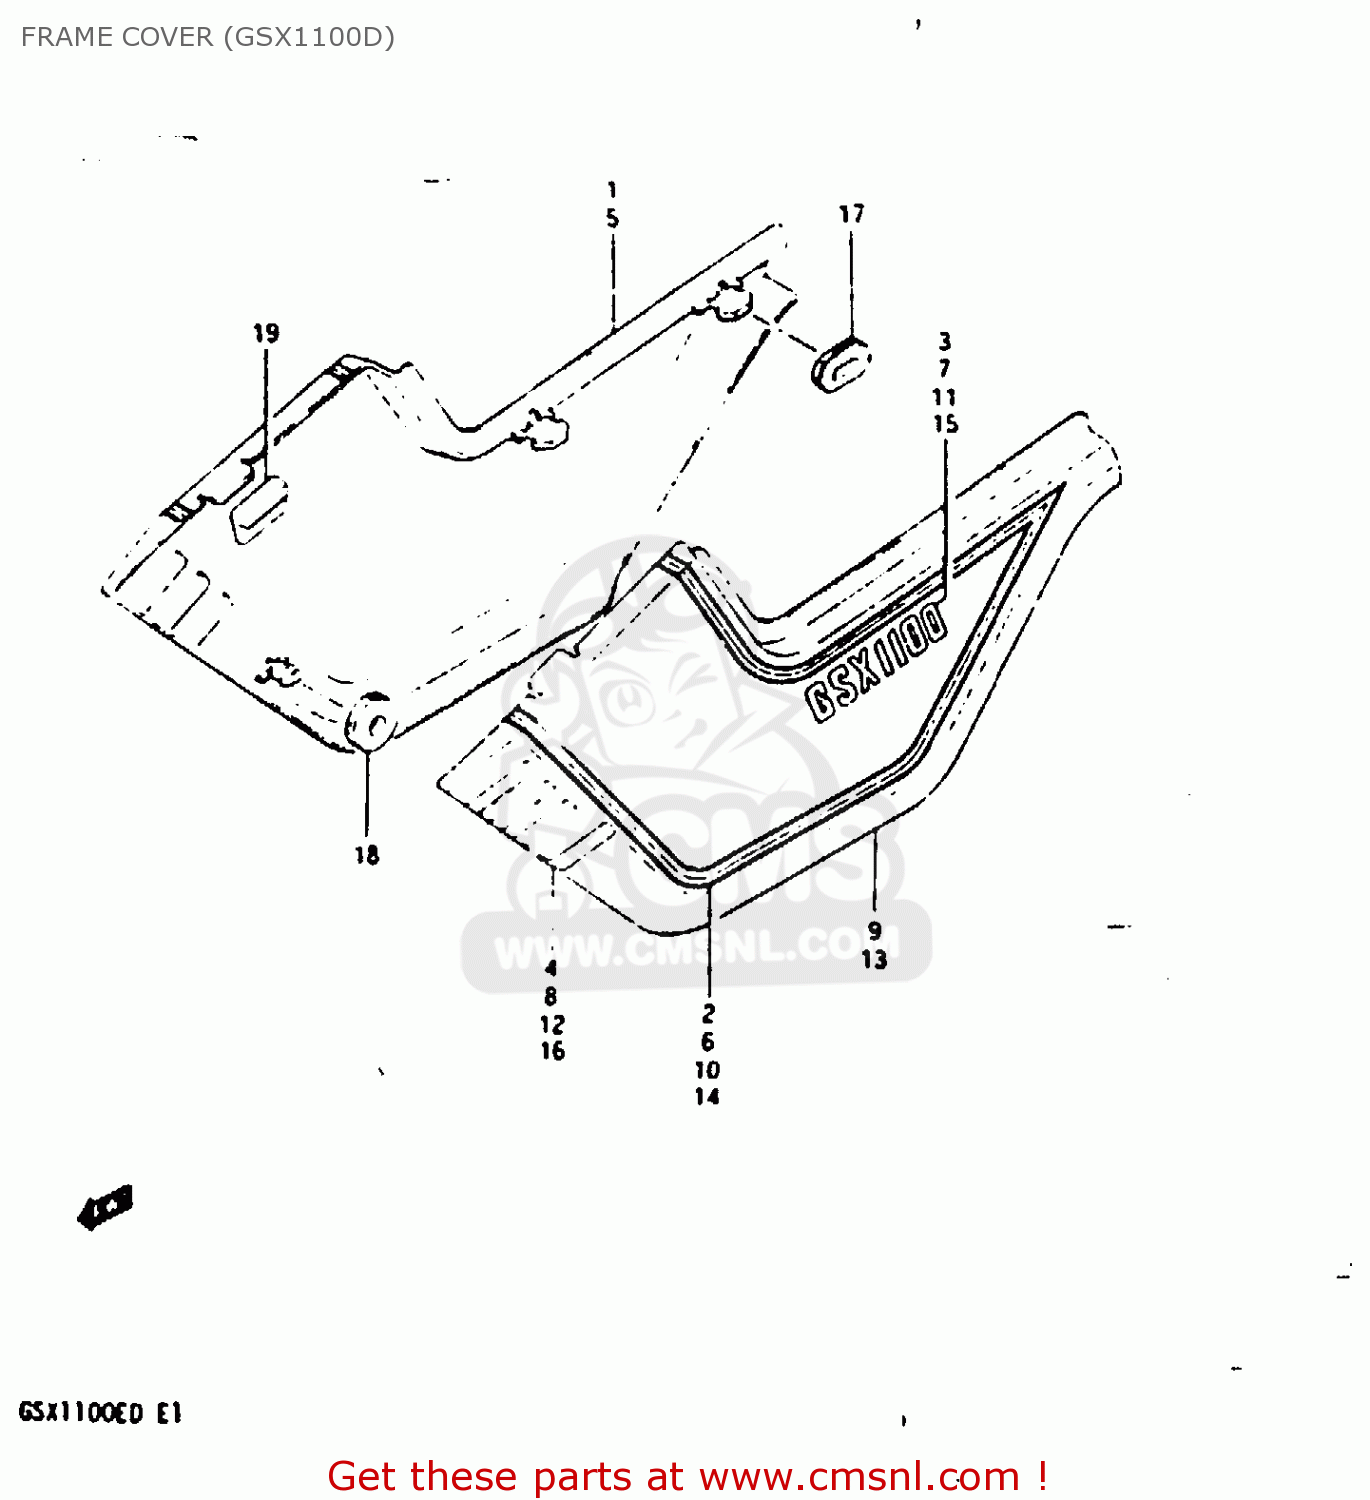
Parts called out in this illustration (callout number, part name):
1	COVER, FRAME RH
2	TAPE SET, FRAME COVER RH
3	EMBLEM, LH
4	LABEL, DENT
5	COVER, FRAME RH
6	TAPE SET, FRAME COVER RH
7	EMBLEM, LH
8	LABEL, DENT
9	COVER, FRAME LH
10	TAPE SET, FRAME COVER LH
11	EMBLEM, LH
12	EMBLEM,FRAME COVER,CENTER
13	COVER, FRAME LH
14	TAPE SET, FRAME COVER LH
15	EMBLEM, LH
16	EMBLEM,FRAME COVER,CENTER
17	CUSHION
18	CUSHION
19	CUSHION,FRAME COVER
